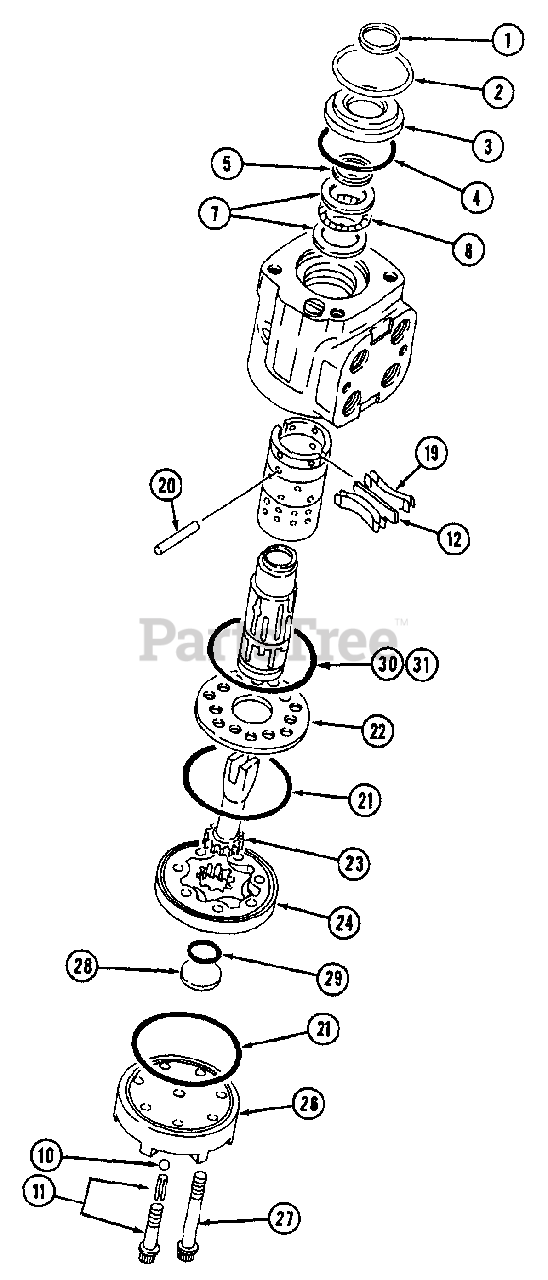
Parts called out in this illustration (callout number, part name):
1	Seal, Dust
2	Ring, Retaining
4	O-Ring
5	Seal, Oil
7	Bearing, Needle
8	Bearing, Needle
11	Retainer, Screw Ass'y.
19	Spring, Centering
21	O-Ring
22	Plate, Spacer
29	O-Ring
30	O-Ring
31	O-Ring
